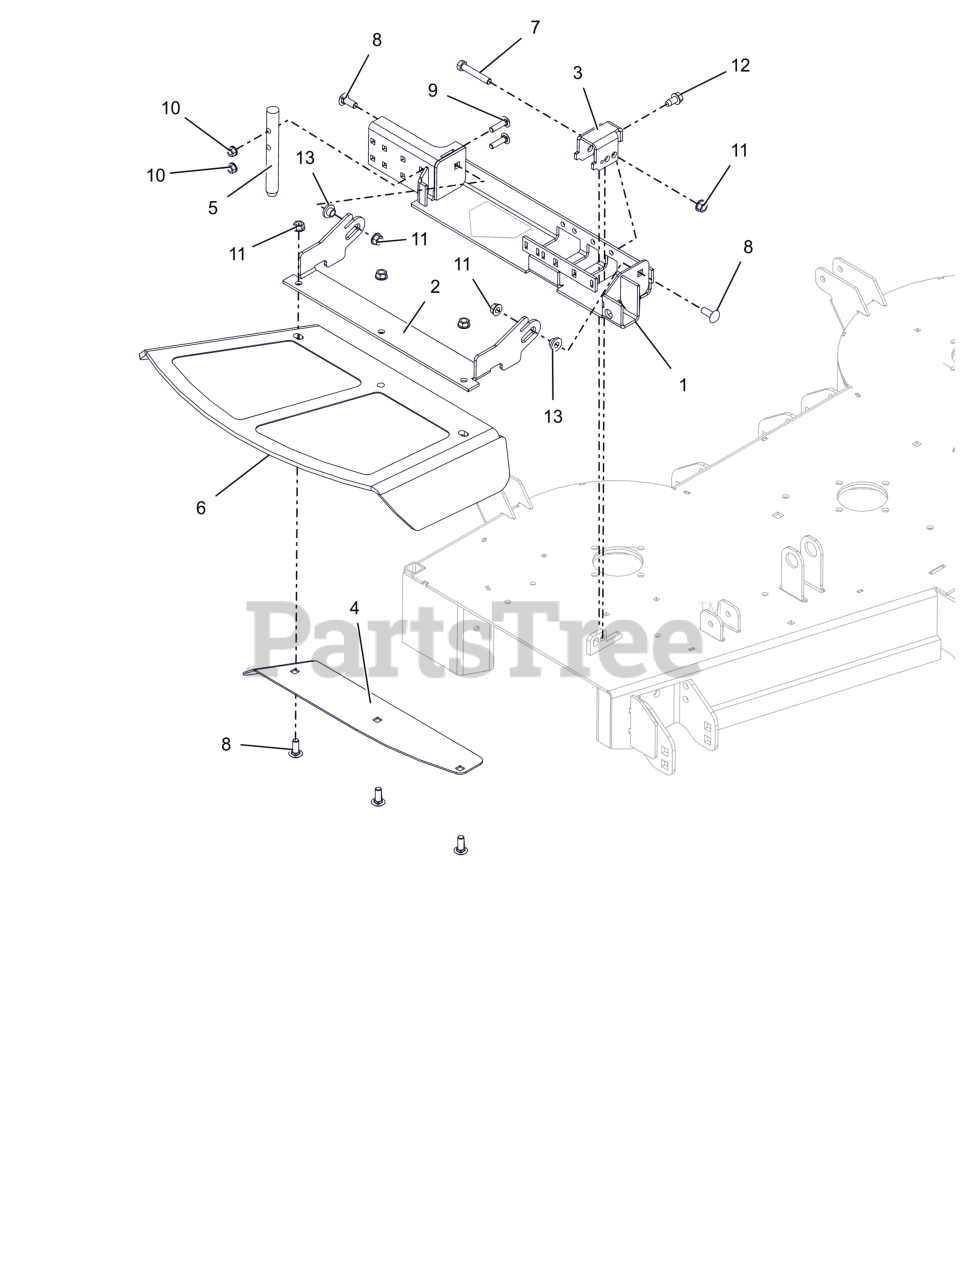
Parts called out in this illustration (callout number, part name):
1	WLDMT, GRASS CATCHER
2	BRKT, 48-60" CHUTE MTG
3	BRKT, DISCH. CHUTE MTG
4	48-60 DISCH CHUTE CLMP PLT-BLK
5	PIN, DISCHARGE CHUTE X-DRILLED
6	CHUTE,48-60" FRMD RUBBER DISCH
7	BLT,HEX .38-16X2.25 G5 ZCC
8	BLT,RHSSN .38-16X1.00 G5 ZCC
9	BTL,RHSSN .313-18 X 1.25 G5 ZCC
10	NUT,LK-CTR-FLG .31-18 GF ZCC
11	NUT-LK-CTR-FLG .375-16 GF ZCC
12	SCR,TAP .375-16X.75 HWH TR ZCC
13	BSHG-FLG .385X.500X.875X.406
